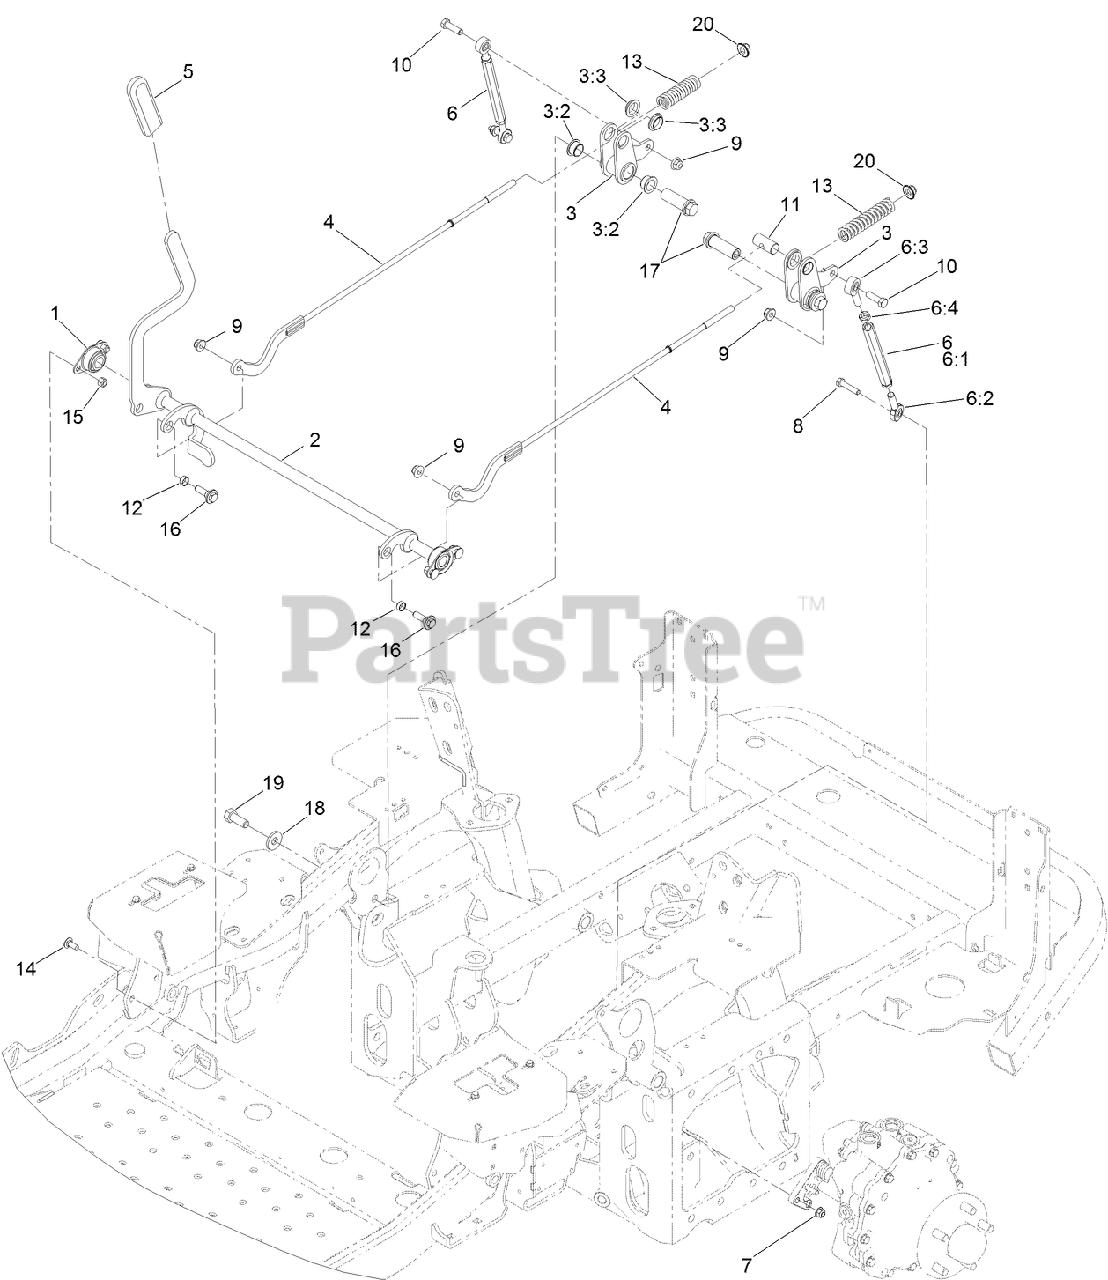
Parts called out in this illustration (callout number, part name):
1	BEARING-FLANGE, SIDE
2	SHAFT-BRAKE
3	BRAKE BELLCRANK ASM
3:2	BUSHING-FLANGE
3:3	BUSHING-FLANGE
4	LINK-BRAKE, UPPER
5	GRIP-LEVER
6	TURNBUCKLE ASM
6:1	TURNBUCKLE
6:2	BEARING-END, LH ROD
6:3	BALLJOINT
6:4	NUT-HJ
7	NUT-HF, NI
8	SCREW-HH
9	NUT-HF, NI
10	SCREW-HH
11	PIN-TRUNION
12	BEARING-SLEEVE
13	SPRING-COMPRESSION
14	SCREW-CARR
15	NUT-LOCK, NI
16	SCREW-SHOULDER, HWH
17	HUB-THREADED
18	WASHER-SPRING
19	SCREW-HH
20	NUT-FLANGE, NI
